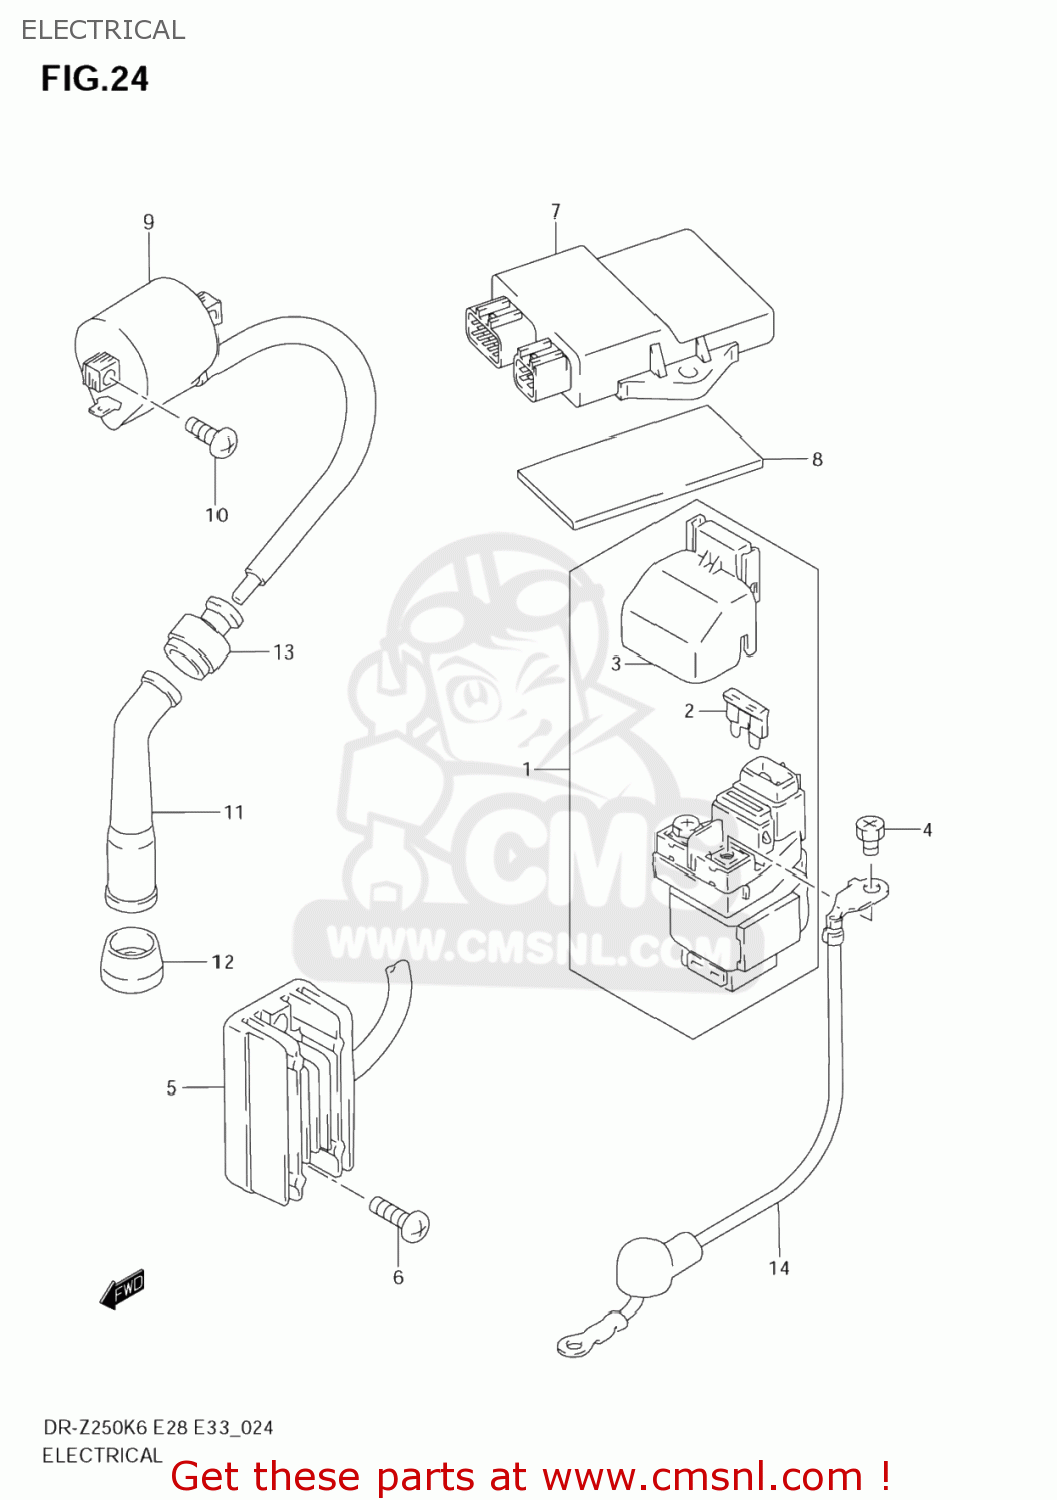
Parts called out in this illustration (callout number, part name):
1	RELAY ASSY,STARTING MOTOR
2	FUSE(10A)
3	COVER
4	SCREW(6X8)
5	RECTIFIER ASSY
6	SCREW
7	CDI UNIT
8	PROTECTOR(170X95X3.0)
9	COIL ASSY,IGNITION
10	SCREW
11	CAP ASSY,SPARK PLUG
12	SEAL,SPARK PLUG
13	SEAL,HIGH TENSION CORD
14	WIRE,STARTER MOTOR
